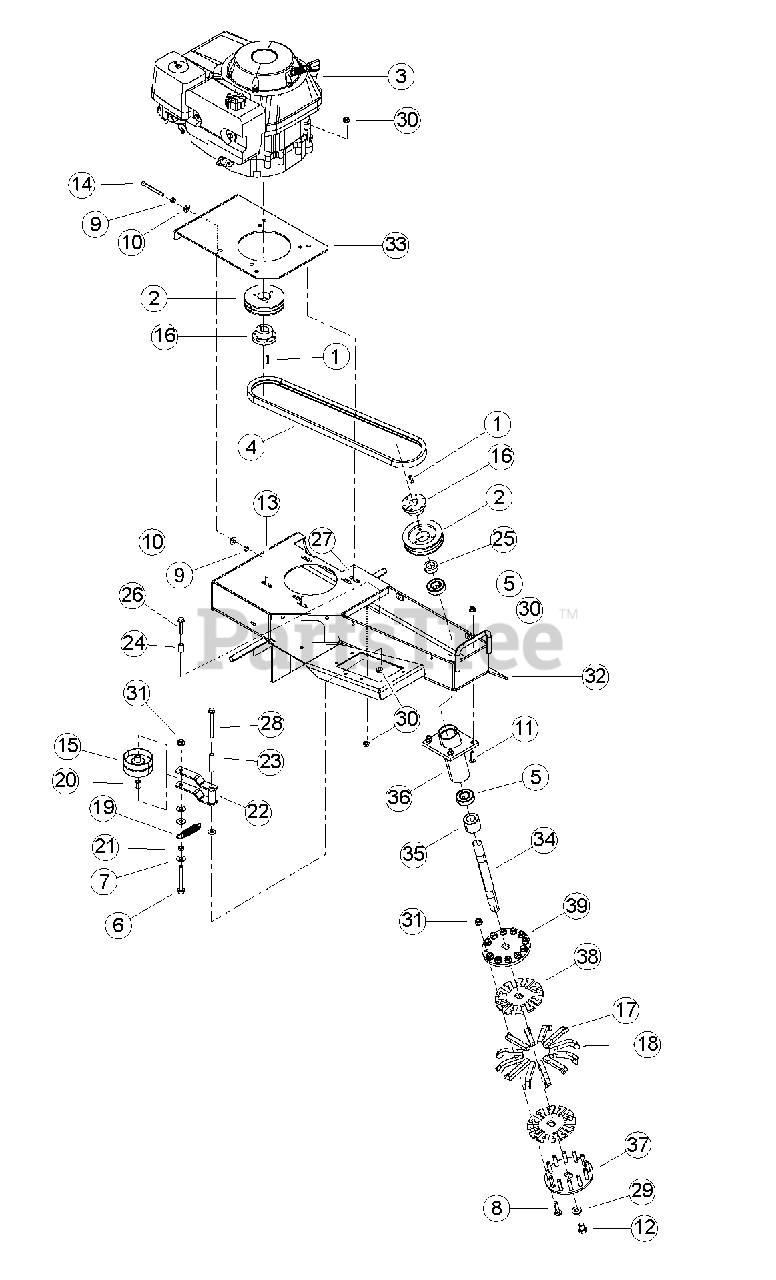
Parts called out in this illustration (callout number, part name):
1	KEY, 1/4 SQ X 1-1/4
2	SHEAVE, 3V4.5-2 GROOVE SH
3	ENGINE, 11 HP HONDA GXV
4	BELT, 3VX530 DOUBLE BANDED
5	BEARING, 1 INCH BALL
6	BOLT, 3/8 X 3 GR5 HEX CAPSCREW ZP
7	WASHER, 3/8 FLAT ZP
8	BOLT, 3/8 X 1 3/4 GR5 CARR BLT ZP
9	NUT, 5/16 HEX NC - ZP
10	WASHER, 5/16 FLAT ZP
11	BOLT, 5/16 X 1-1/4 GR5 ZP CRG
12	BOLT, 1/2-20 X 3/4GR5 HHCS NF ZP
13	BOLT, 5/16 X 1-1/4 HCS NF GR5 ZP
14	SCREW, 5/16 X 3 SQ HD SET
15	PULLEY, 3-1/4 FLAT IDLER
16	BUSHING, SH 1 INCH
17	STUMP CUTTER TEETH, STRAIGHT
18	STUMP CUTTER TEETH, R.H.
19	SPRING, 3/4OD EXTENSION
20	3/4 LONG IDLER SPACER TUBE
21	SPACER IDLER PIVOT
22	WELDMENT, 2 BELT IDLER
23	PIVOT TUBE
24	SPACER, .54 X .88
25	SPACER, 1-1/2 X 1/2
26	BOLT, 5/16 X 1-3/4 FLANGE NC
27	BOLT, 5/16 X 2-1/4 FLANGE NC
28	BOLT, 5/16 X 3-1/2 SERR FLANGE NC
29	WASHER, 1/2 HI-STRENGTH SAE ZP
30	NUT, 5/16-18 NYLOCK-FLANGE
31	NUT, 3/8-16 NYLOCK FLANGE
32	WELDMENT, STUMPGRINDER FRAME
33	PLATE, ENGINE SLIDE
34	SPINDLE, SG 12 BLADE
35	TUBE, SPACER 1-3/4 X 1.520
36	WELDMENT, SPINDLE HUB
37	PLATE, COVER STUMPGRINDER HEAD
38	PLATE, SPACER STUMPGRINDER HEAD
39	PLATE, DISK STUMPGRINDER HEAD
